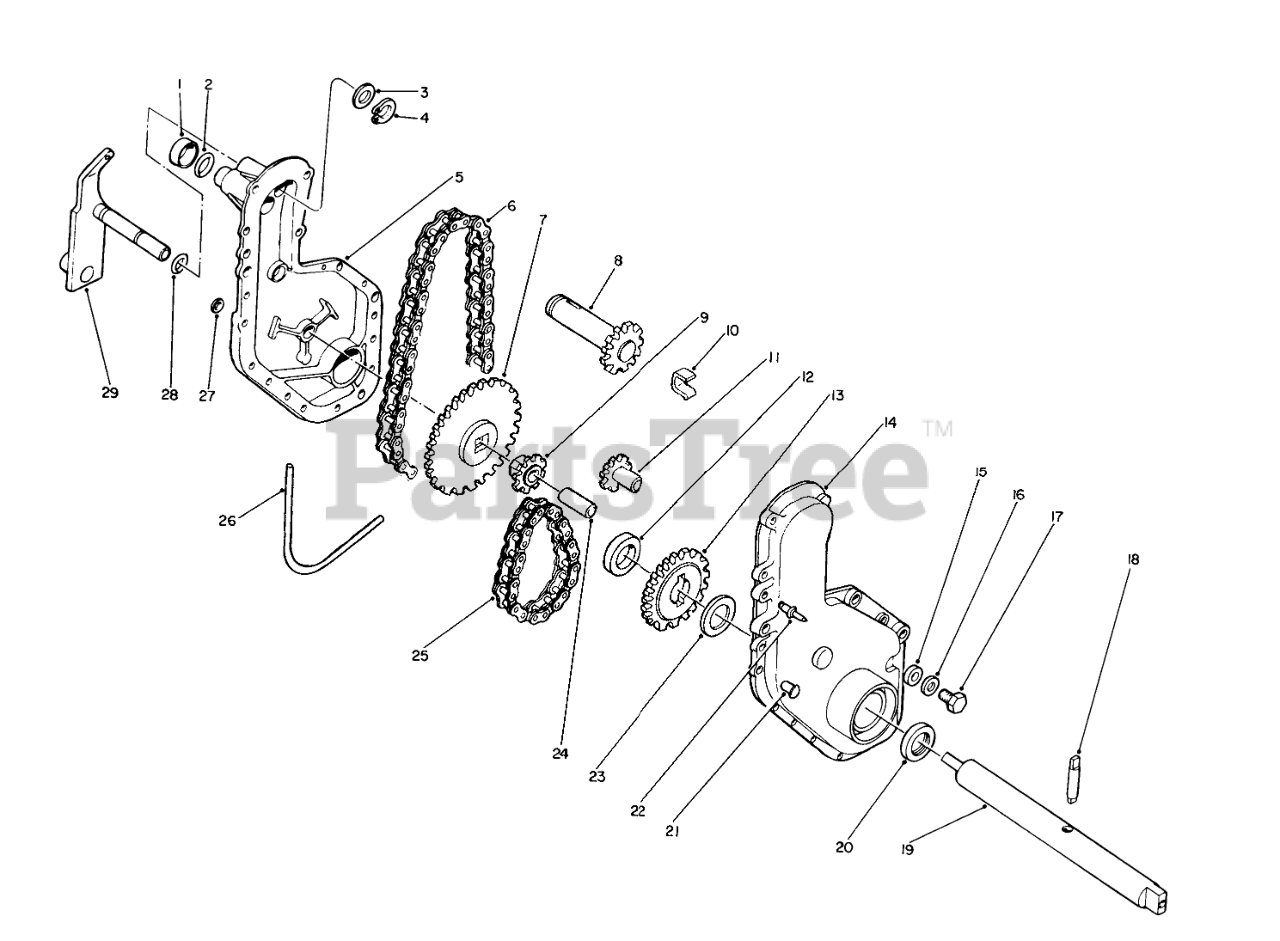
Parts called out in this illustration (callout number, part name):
1	Seal Cup
2	O-Ring
3	Idler Washer
4	Retaining Ring
5	Chain Case L.H. W/Bearings
6	Chain-Upper
7	Sprocket-42 Tooth
8	Input Shaft
9	Sprocket-8 Tooth
10	"U" Clip
11	Idler Sprocket-9 Tooth
12	Washer
13	Sprocket-19 Tooth
14	Chain Case R.H.
15	Nylon Washer
16	WASHER-PLAIN
17	SCREW-HH
18	Drive Pin
19	Tine Shaft
20	Seal
21	Rivet
22	Pop River
23	Washer
24	Shaft-Sprocket
25	#40 Roller Chain
26	Gasket
27	WASHER-PLAIN
28	O-Ring
29	Idler Arm
